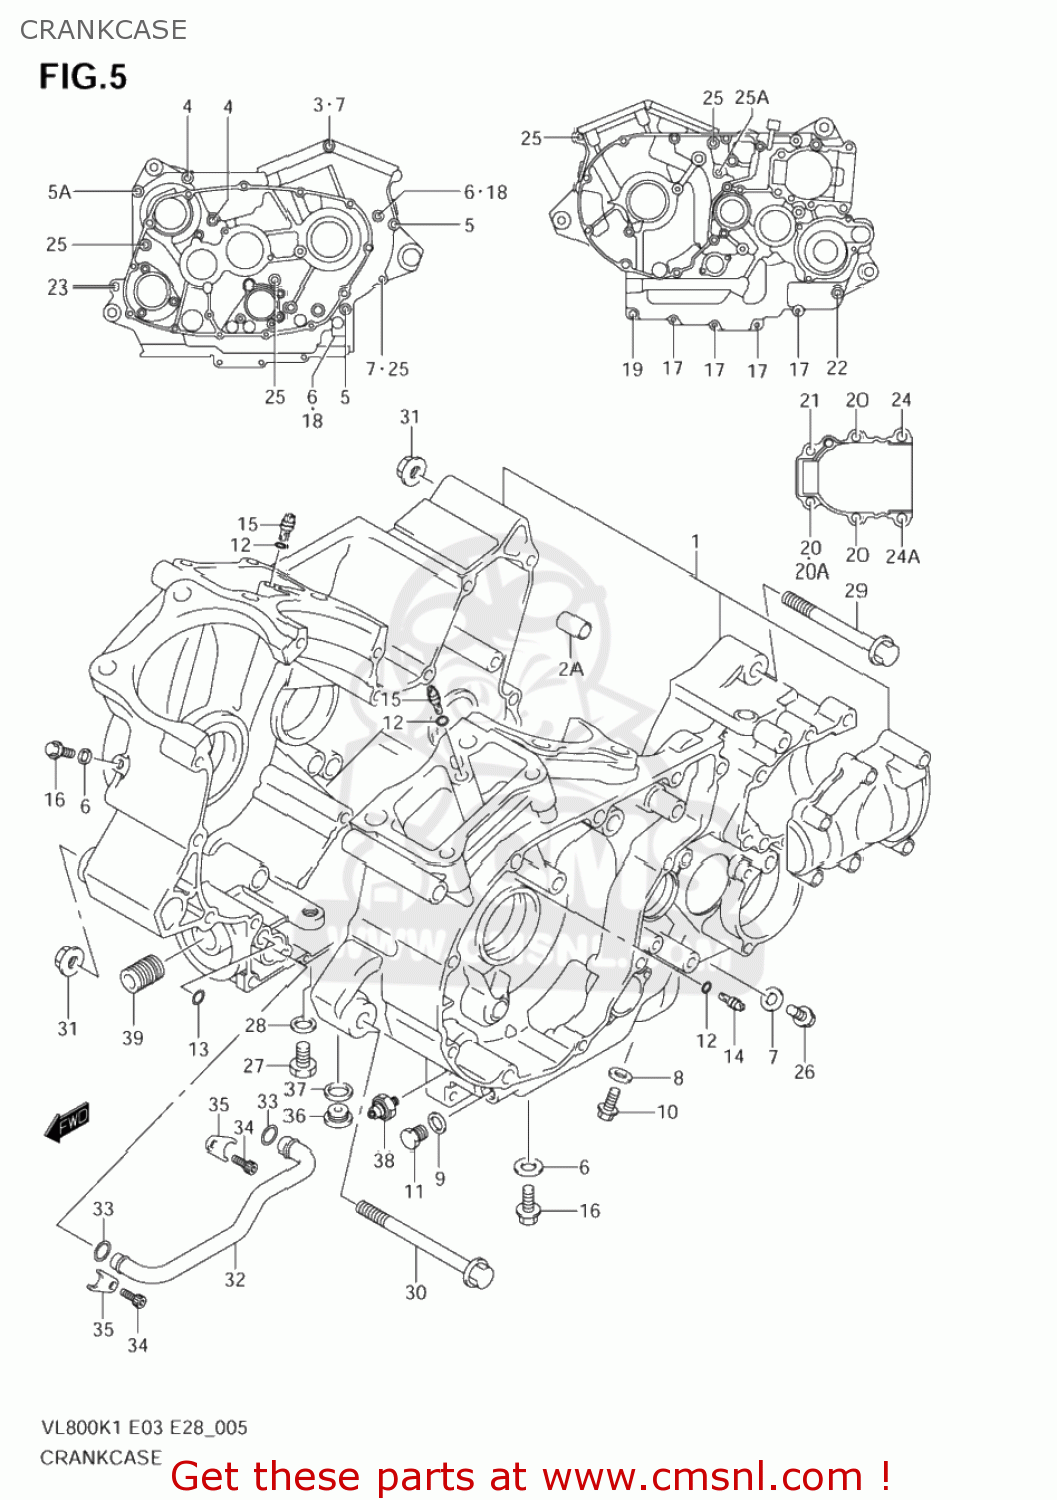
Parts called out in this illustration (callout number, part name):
1	CRANKCASE SET
2	WASHER(48.1X64X1.94)
2A	PIN(8.4X11X20)
3	BOLT(8X160)
4	BOLT(8X120)
5	BOLT(8X105)
5A	BOLT(8X95)
6	GASKET(5.8X13X1.2) (NAS)
7	GASKET(8.2X16X1) (NAS)
8	GASKET(10X14X3.6) (NAS)
9	GASKET(13.8X18.8X4.8) (NAS)
10	PLUG(10X12)
11	PLUG(14X12)
12	O RING(D:1.2,ID:4)
13	O RING(D:1.9,ID:12.6)
14	JET,OIL GALLERY
15	JET,AIR(14)
16	BOLT
17	BOLT
18	BOLT
19	BOLT
20	BOLT
20A	GASKET(8.2X16X1) (NAS)
21	BOLT
22	BOLT
23	BOLT
24	BOLT
24A	BOLT
25	BOLT
25A	BOLT
26	PLUG
27	PLUG,12X20
28	GASKET(12.1X16.2X3.7) (NAS)
29	BOLT(10X135)
30	BOLT(10X160)
31	NUT
32	PIPE,OIL GALLERY
33	O RING(D:3.1,ID:14.8)
34	BOLT(6X12)
35	CLAMP,OIL PIPE
36	PLUG,16X8
37	GASKET(16X22X2) (NAS)
38	SWITCH ASSY,OIL PRESSURE
39	UNION,OIL STAND
